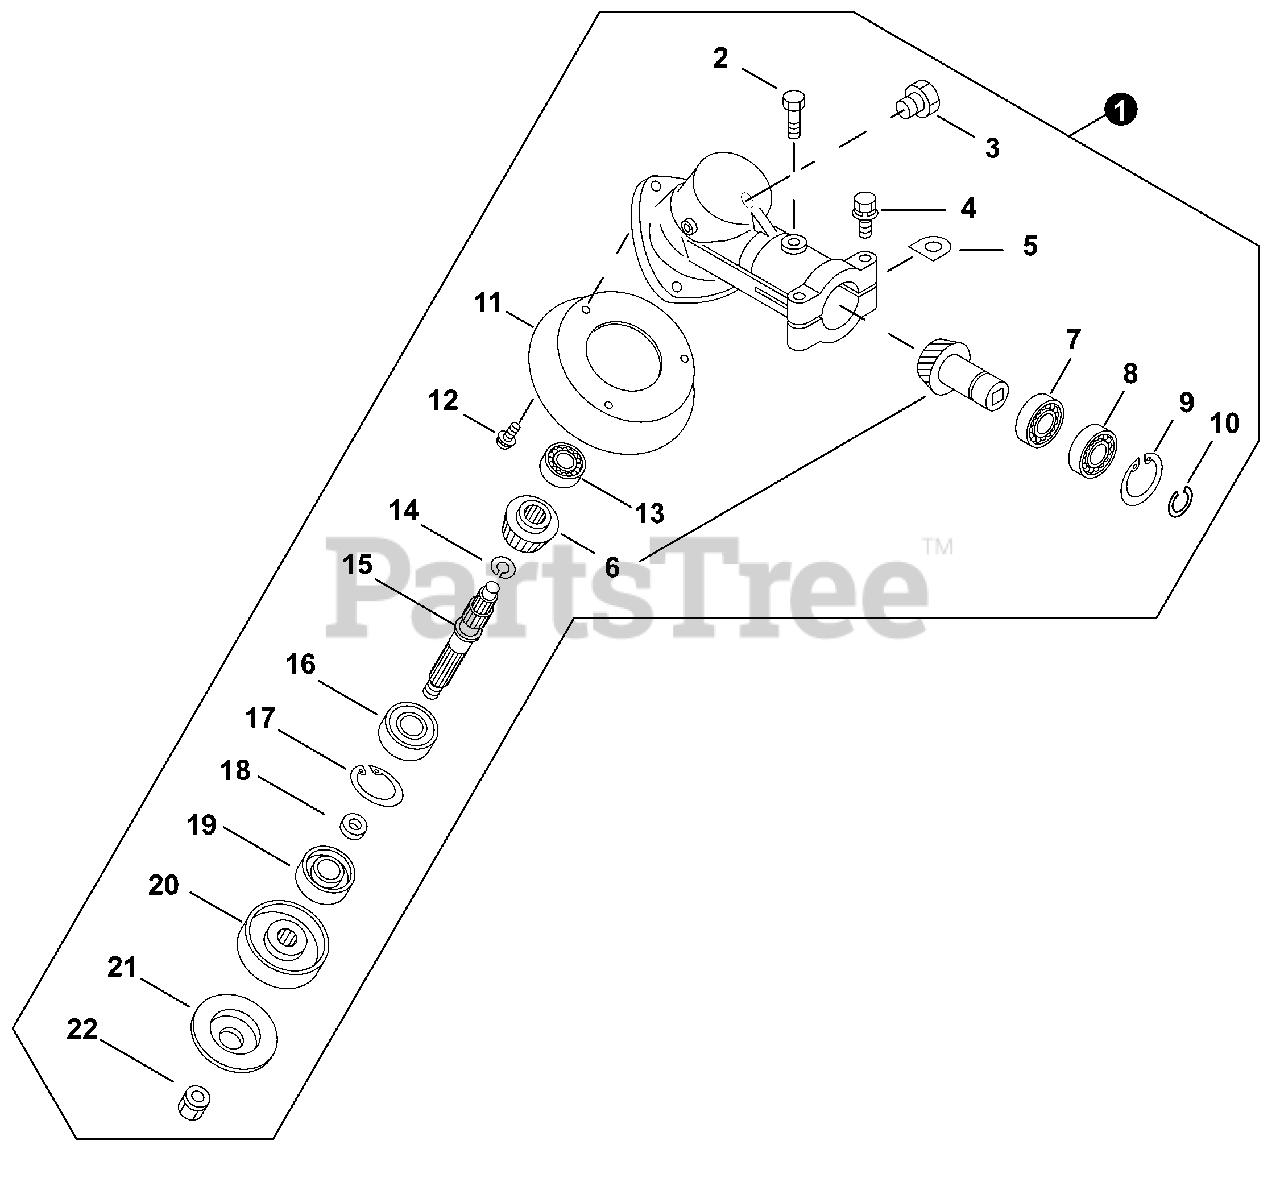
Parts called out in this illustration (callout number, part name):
1	GEAR CASE ASSY
3	BOLT M8×8
4	BOLT M5×30
5	D-WASHER
6	GEAR SET
7	BEARING, BALL 6001
8	BEARING, BALL 6001
9	RING, SNAP 28
10	RING, SNAP 12
11	COVER, GEAR CASE
12	SCREW 5×20
13	BEARING, BALL 6000
14	RING, SNAP Ø12
15	SHAFT, GEAR
16	BEARING, BALL 6201
17	RING, SNAP Ø32
18	SPACER 11.8×15×9
19	SEAL, OIL 22
20	PLATE, ADAPTOR - UPPER
21	PLATE, ADAPTOR - LOWER
